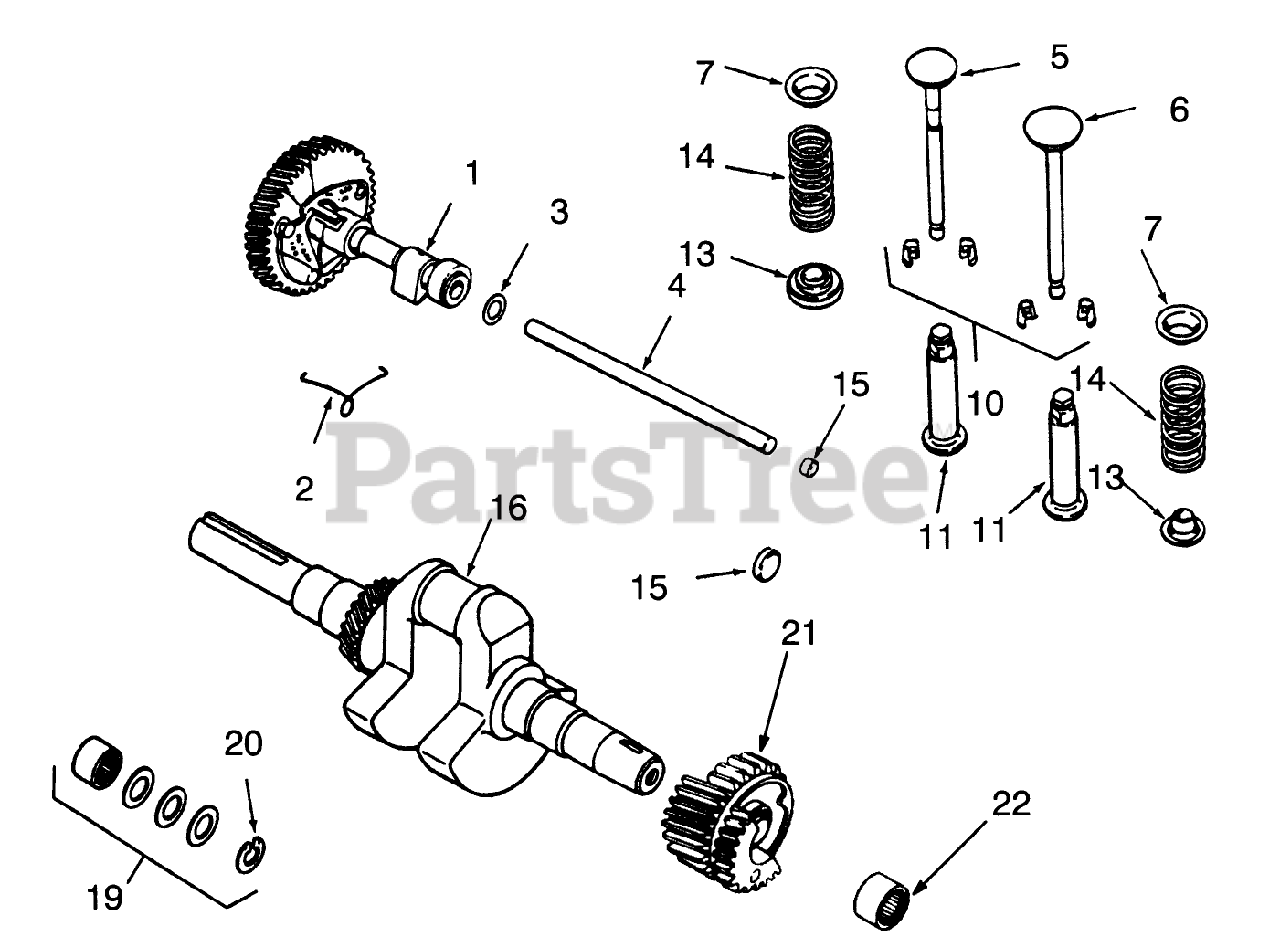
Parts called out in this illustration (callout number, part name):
1	KOHLER 47-010-11
2	KOHLER 47-089-01
3	KOHLER 275066
4	KOHLER 47-380-09
5	KOHLER 237672
6	KOHLER 235582
7	KOHLER 235011
10	KOHLER 41-755-10
11	KOHLER D-235327
13	KOHLER 52-413-01
14	KOHLER 235168
15	KOHLER X-702-3
16	KOHLER 45-142-21
19	KOHLER 47-755-01
20	KOHLER X-269-34
21	KOHLER 45-043-03
22	KOHLER 47-030-01
